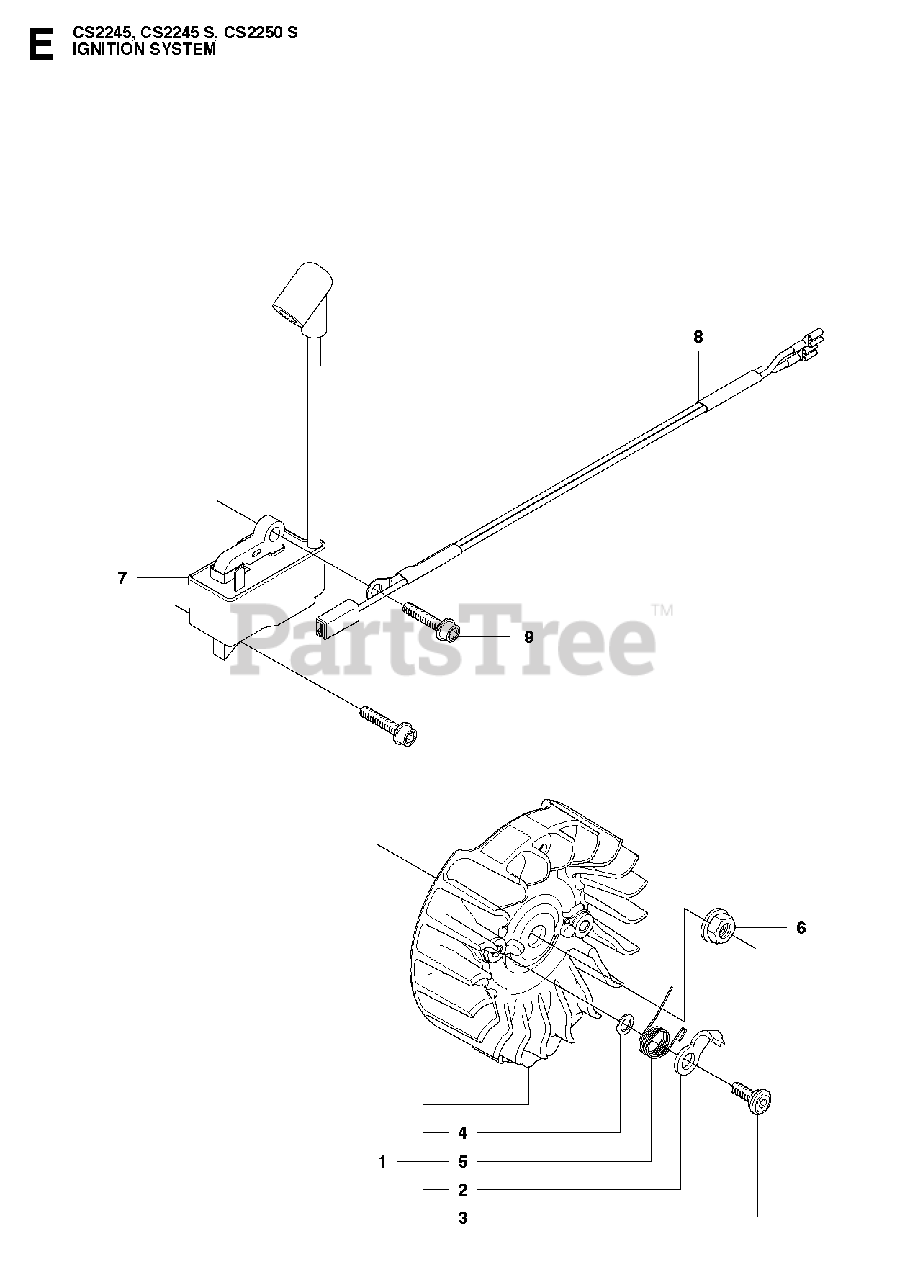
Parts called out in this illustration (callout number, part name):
1	FLYWHEEL ASSY
2	PAWL
3	PIN, STARTER CATCH
4	WASHER
5	SPRING
6	NUT W/ WASHER
7	IGNITION MODULE
8	WIRING ASSY
